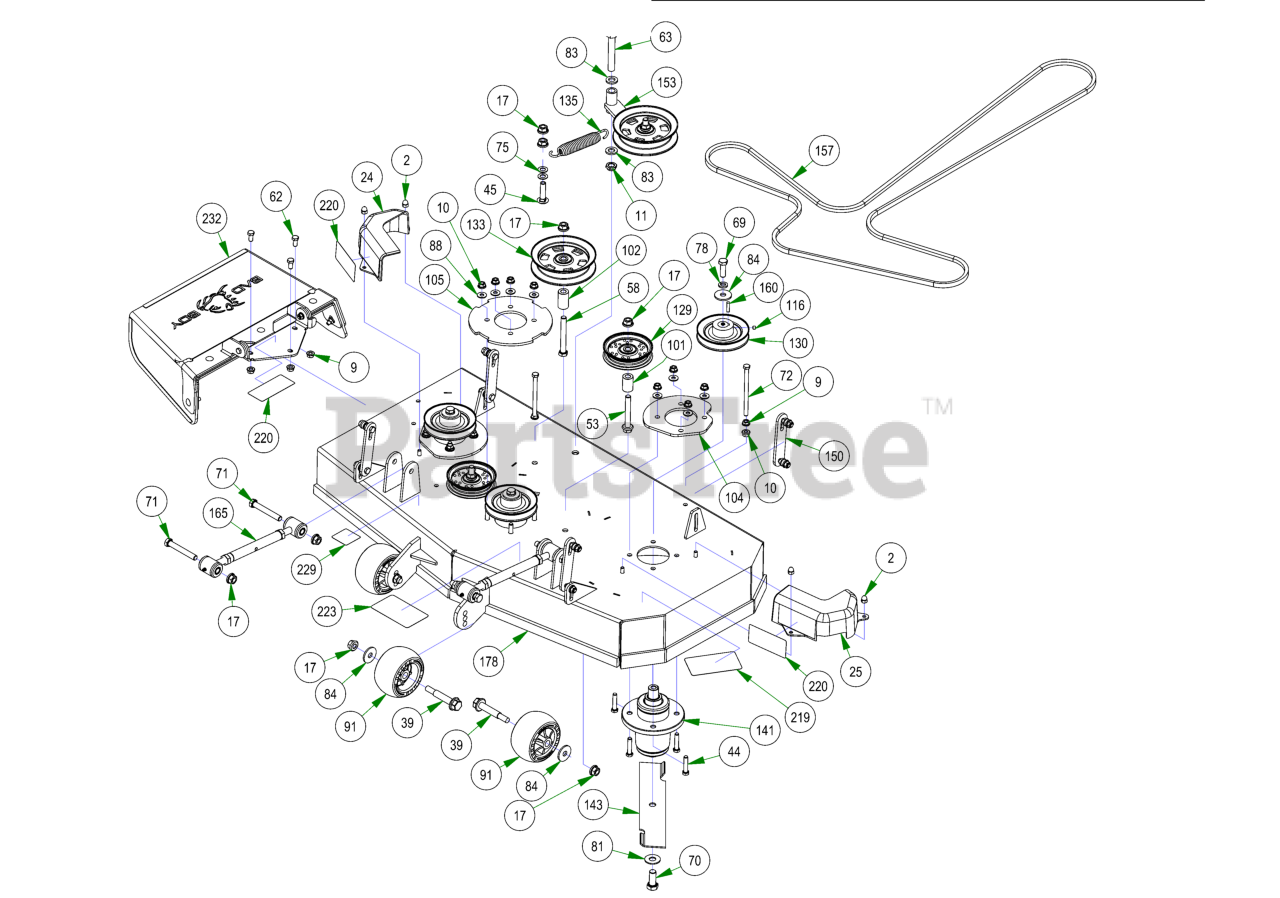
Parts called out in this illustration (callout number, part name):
2	5/16-18 ACORN NUT HIGH-CROWN ZC
9	3/8-16 HEX SERRATED FLANGE NUT HARD/ZINC
10	3/8-16 NYLON INSERT FLANGE LOCKNUT (GR.F) ZINC
11	5/8-11 NYLON INSERT JAM LOCKNUT ZINC
17	1/2-13 NYLON INSERT FLANGE LOCKNUT ZINC
24	pulley cover chute side
25	pulley cover non-chute side
39	Deck Wheel Bolt
44	3/8-16 X 1-3/4 HEX C/S (GR.5) ZC
45	1/2-13 X 2 CARRIAGE BOLT ZINC
53	1/2-13 X 3-1/2 HEX FLANGE BOLT (GR.8) ZINC
58	1/2-13 X 4 HEX CAP SCREW (GR.8) ZINC YELLOW
62	3/8-16 X 3/4 HEX CAP SCREW (GR.5) ZINC
63	5/8-11 X 4 HEX CAP SCREW (GR.8) ZINC YELLOW
69	1/2-20 X 1-1/2 HEX CAP SCREW (GR.5) ZINC
70	5/8-18 X 1-1/2 HEX CAP SCREW (GR.8) ZINC YELLOW
71	1/2-13 X 3-1/2 HEX CAP SCREW (GR.5) ZINC
72	3/8-16 X 5-1/2 HEX CAP SCREW (GR.5) ZINC
75	.517 SQ WDTH ID X .937 OD X .060 THICK F/W PHOS/OIL
78	1/2 SPLIT LOCKWASHER (GR.8) ZINC/YELLOW
81	5/8 USS FLAT WASHER (1-3/4" OD) GR.8 ZINC YELLOW
83	.635 ID X 1.120 OD X .140 THICK FLAT WASHER NYLON
84	1/2 BELLEVILLE WASHER (1-5/8 OD X .140 THK) ZINC
88	5/16 USS FLAT WASHER (7/8 OD) ZINC
91	Deck Wheel
101	.502 ID X .750 OD X 1.500 Long Spacer
102	1 3/4" Pulley Spacer
104	42&48 Deck Spindle Support Plate
105	Deck Spindle Support Plate
116	5/16-24 X 1/4 SOCKET SET SCREW (CUP PT) PLAIN
129	4 3/4 Idler Pulley - ABFI-76
130	5" Spindle Deck Pulley
133	5-3/4 Idler Pulley
135	Deck Idler Spring
141	OUTLAW SPINDLE ASSEMBLY
143	42'' High lift Blade
150	Deck Hanger Assembly
153	2017 54"/48" Deck Idler Assembly
160	1/4 X 1 SQ MACHINERY KEY 1018 STL PLN
165	2018 Maverick Turnbuckle (Top Link)
178	42" Deck Shell
219	2018 42" MZ/Comp Out Deck Decal
220	Danger Decal-Spindle/Discharge
223	Deck Belt Route Decal
229	Deck Impact Patent Decal 9591803
232	ZT Chute Assembly
